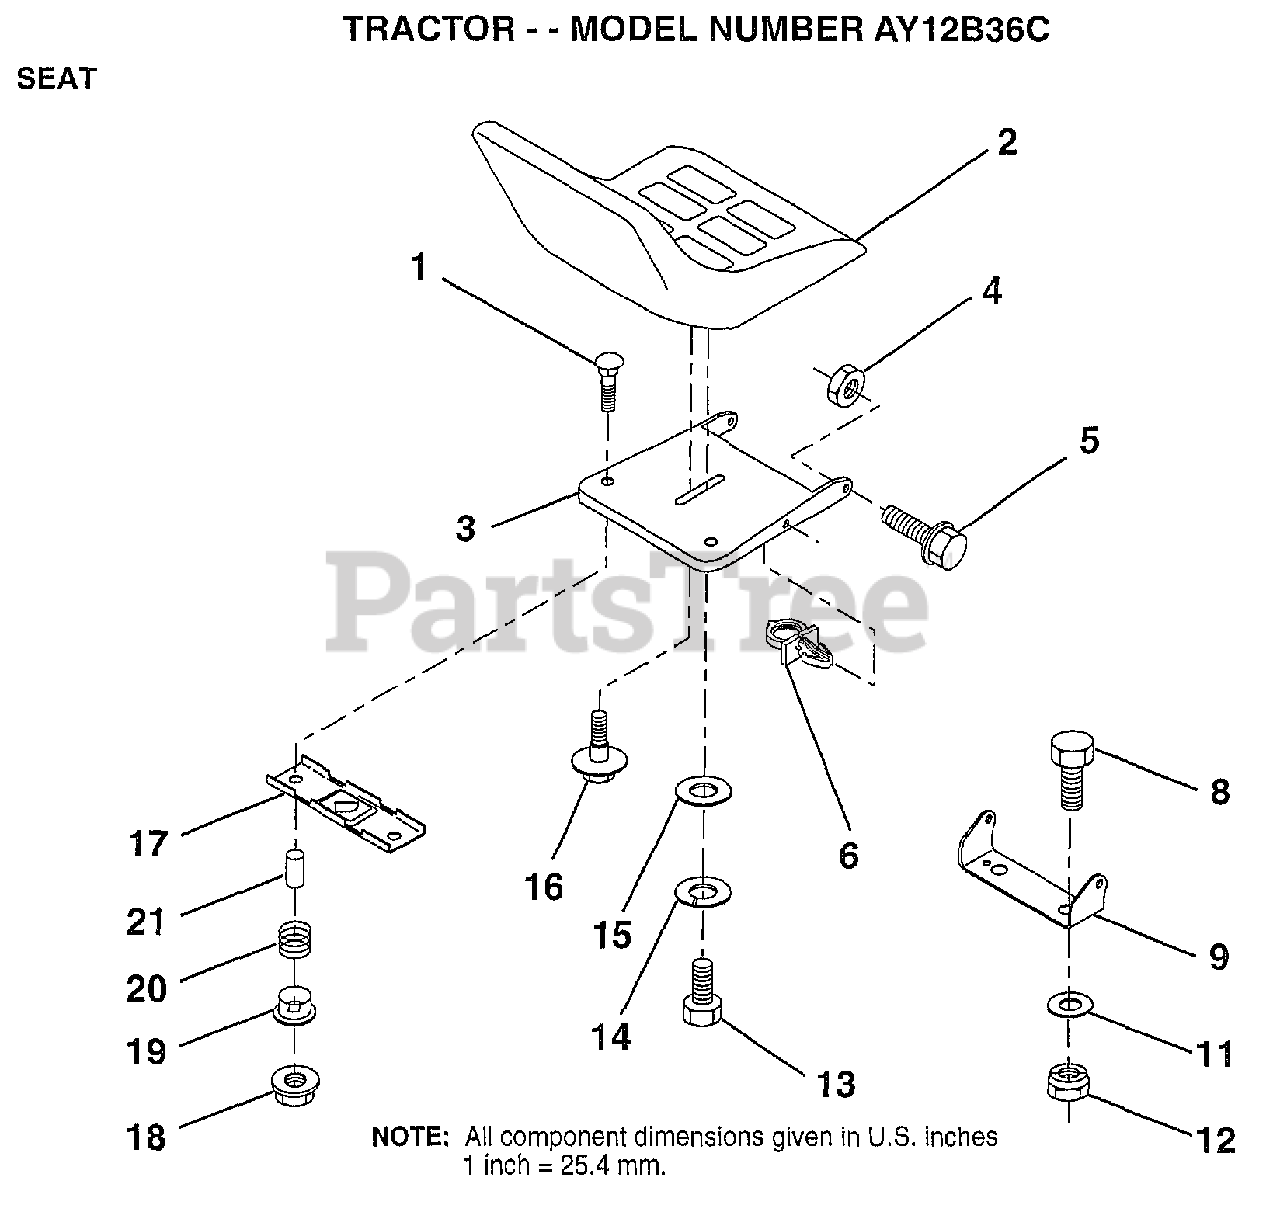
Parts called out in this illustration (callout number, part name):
1	BOLT-RD HD SQ NK
3	PAN-SEAT
4	NUT
5	"BOLT,SHOULDER"
6	CLIP.PUSH-IN.HING
8	BOLT
9	BRACKET PVT SEAT
11	WASHER
12	NUT
13	BOLT
14	LOCKWASHER
15	WASHER
16	"BOLT,SHOULDER"
17	BRKT SWITCH
19	BUSHING
20	SPRING
21	SPLIT SPACER
